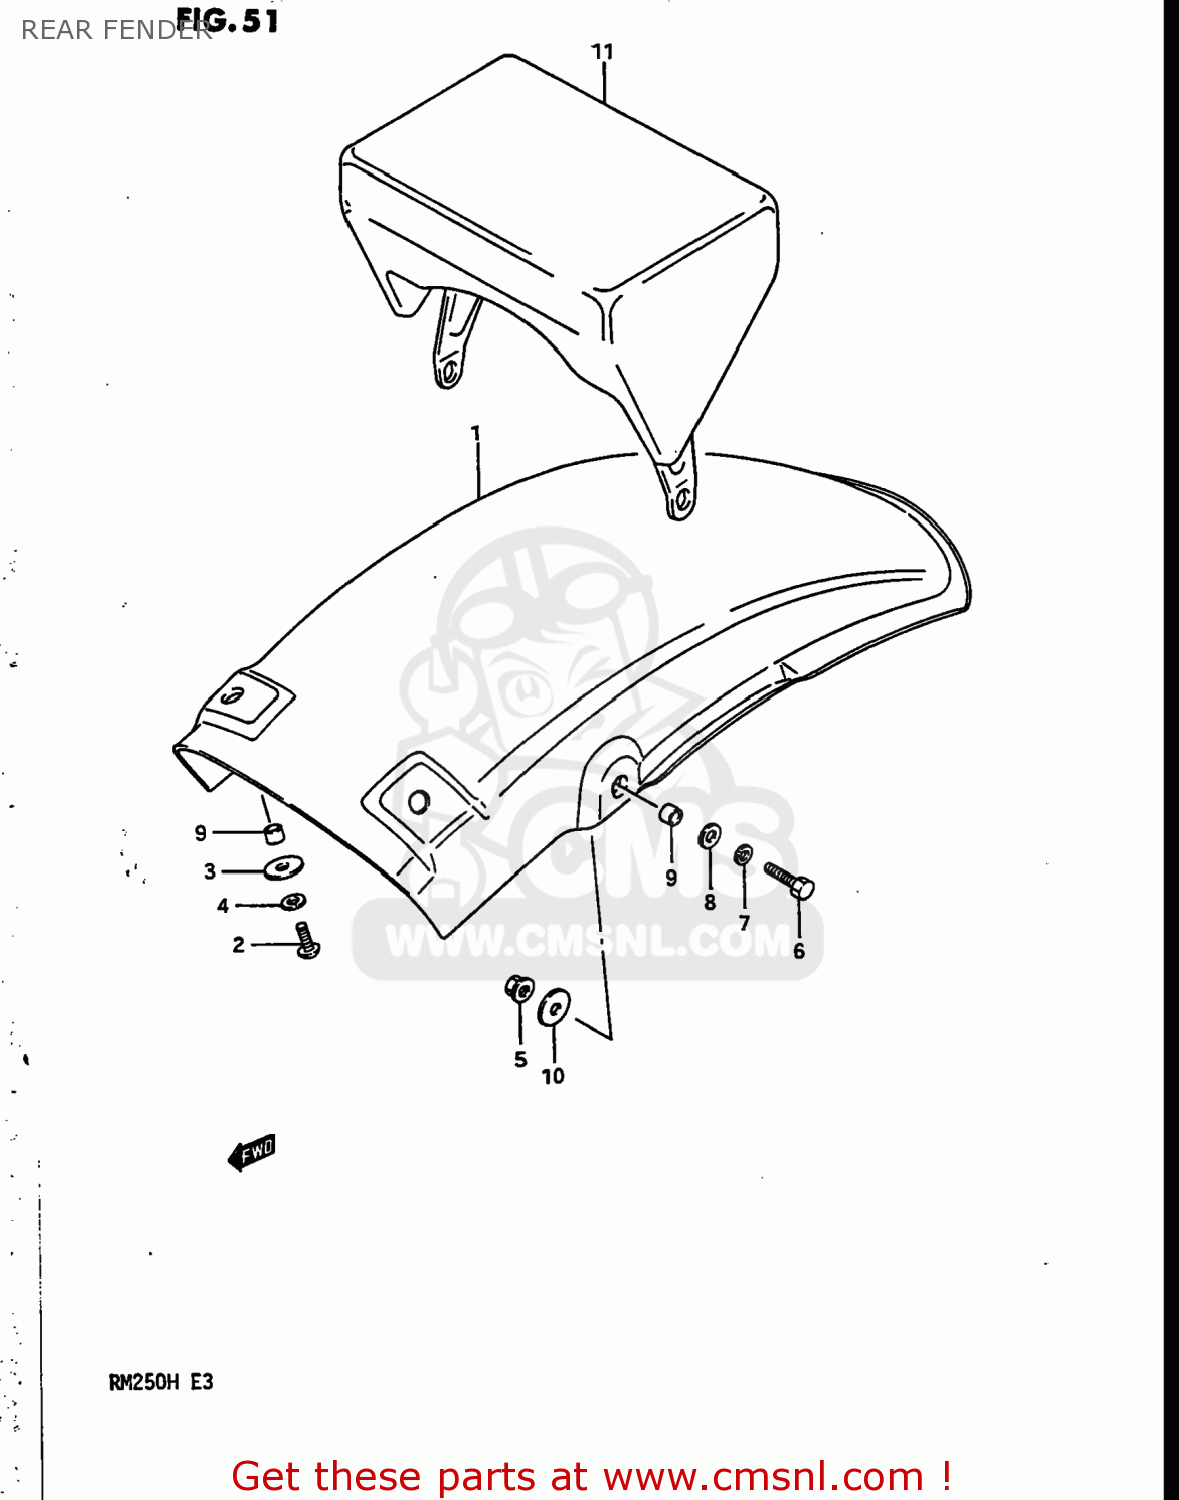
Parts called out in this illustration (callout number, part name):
1	FENDER,REAR
2	SCREW
3	WASHER
4	WASHER,LOCK
5	NUT
6	BOLT
7	WASHER,LOCK
8	WASHER
9	SPACER
10	WASHER (6.5X20X1.2)
11	BAG ASSEMBLY,SEAT TAIL
